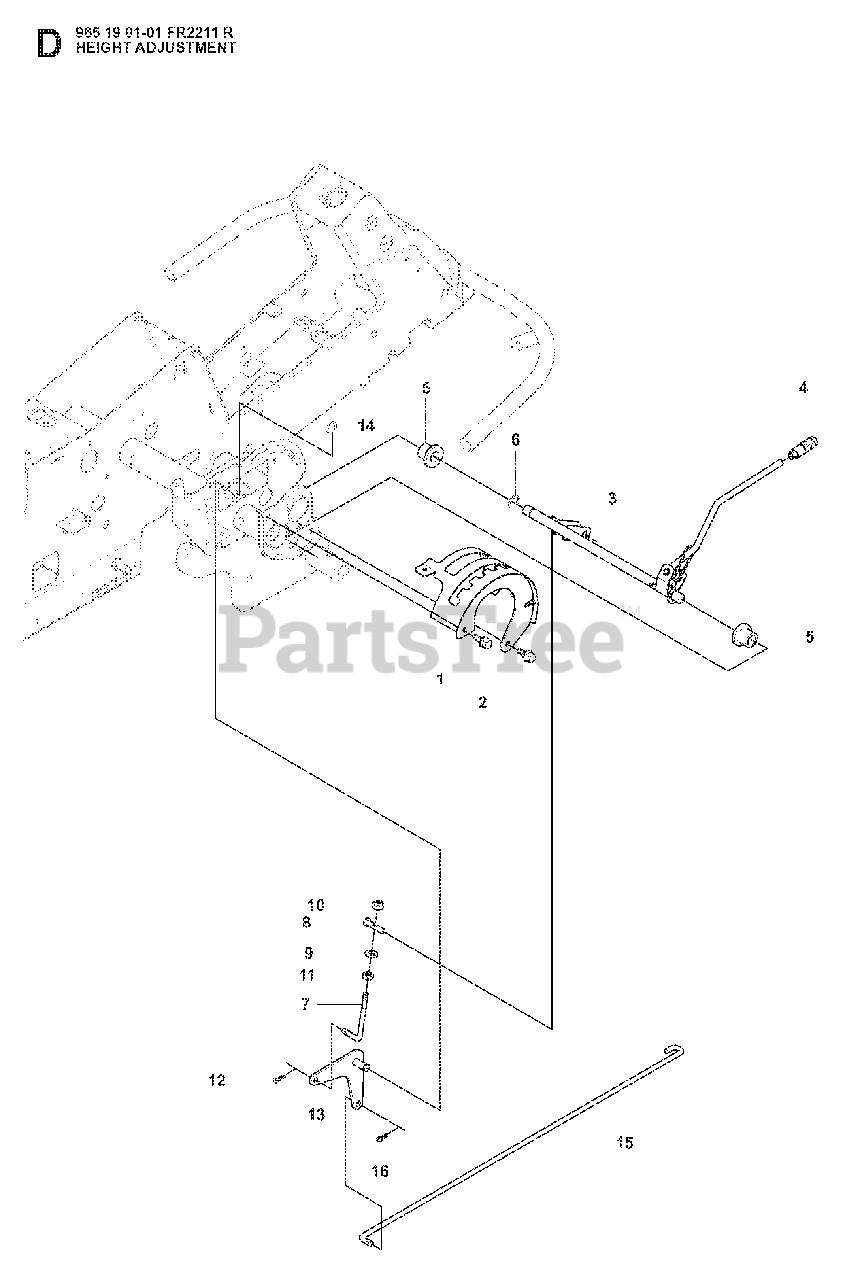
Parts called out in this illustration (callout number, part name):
4	GEAR STICK KNOB
5	BUSHING
9	WASHER
10	LOCKNUT M8
11	NUT
12	SPLIT PIN
14	RETAINING RING
16	SPLIT PIN
